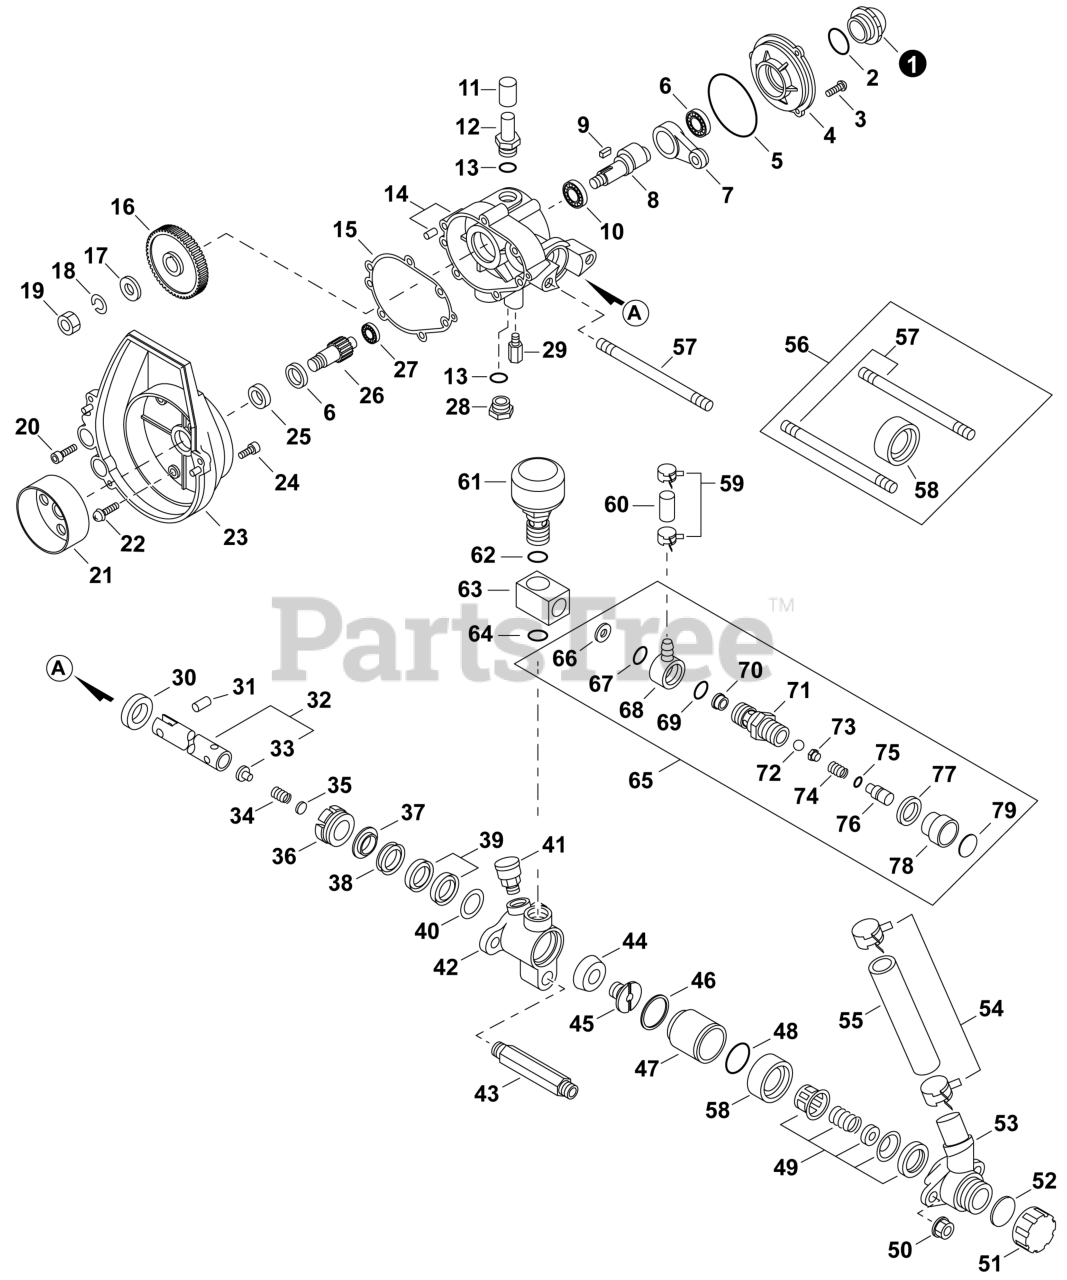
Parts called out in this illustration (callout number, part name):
1	GAUGE, OIL
3	SCREW 4x12
4	COVER, PUMP
6	BEARING, BALL 6001
7	ROD, CONNECTING
8	CRANKSHAFT
10	BEARING, BALL 6201
12	BOLT, OIL
14	CASE KIT, PUMP
15	GASKET, PUMP
16	GEAR, SPUR
17	WASHER 8.5x16x1.2
18	WASHER, SPRING 8
20	BOLT 5x25
21	DRUM, CLUTCH
22	SCREW 5x25
23	COVER, FAN
24	BOLT 5x18
25	SEAL, OIL
26	SHAFT, PINION
27	BEARING, BALL 609
28	CAP, DRAIN
30	SEAL, OIL
31	PIN, PISTON
32	PLUNGER SET, W/SPRING HOLDER
33	HOLDER, SPRING
34	SPRING, VALVE
38	PACKING, GREASE
39	PACKING SET
41	CUP ASSY, GREASE
42	CYLINDER
43	CONNECTOR, HOSE
44	PACKING, PISTON
45	SEAT, VALVE
